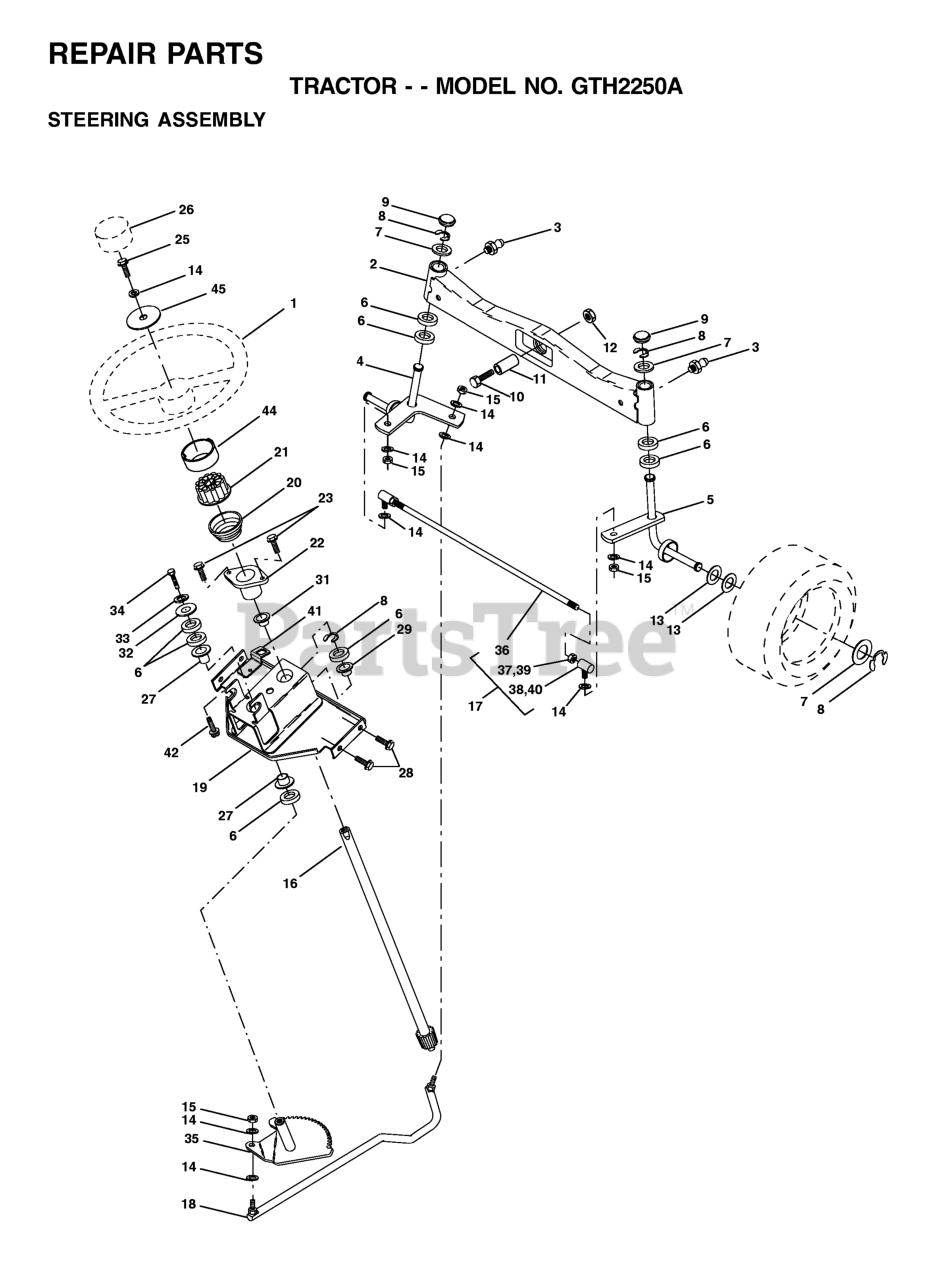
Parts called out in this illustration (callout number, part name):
1	STEERING WHEEL
2	AXLE.FRONT.CAST.MACHINE.W/ZERK
3	ZERK M
4	SPINDLE ASSY LH
5	SPINDLE ASM RH
6	THRUST WASHER
9	CAP.SPINDLE.BLACK
10	Bolt, Hex 5/8 -11 x 2 - 3/4 Gr. 5
11	TUBE, PIVOT AXLE
12	NUT-LOC,FLANGE LT
14	WASHER, LOCK 3/8
15	GRIPCO NUT
16	SHAFT ASM, STEERING
17	ROD ASSY/TIE BALL
18	DRAGLINK, BALL JOINT (3SPG1401
19	SUPPORT ASM., STEERING VGT
20	BOOT, STEERING
21	STEERING WHEEL ADAPTOR
22	BUSHING, STRG. BLK
23	SCREW.TT.#10-32X.5.3/8.FLANGE
26	CAP.WHEEL.STEERING.GREY
27	BRNG T
28	SCREW, 3/8-16X3/4
29	BEARING-FLANGE GT
31	BUSHING.NYLINER.
33	WASHER.LOCK.HVY.HLCL.SPR.5/16
34	BOLT.FIN.HEX.5/16-18X3/4
35	GEAR.ASM.SECTOR.
36	TIE ROD
38	JOINT
41	BRACKET INTERLOCK
42	Screw 5/16-18 x 1/2 Hex, Self Tapping 5/16-18 x 1/2
44	EXTENSION STEERING PREMIUM
45	Washer 13/32 x 1-1/20 x 11 Gauge
